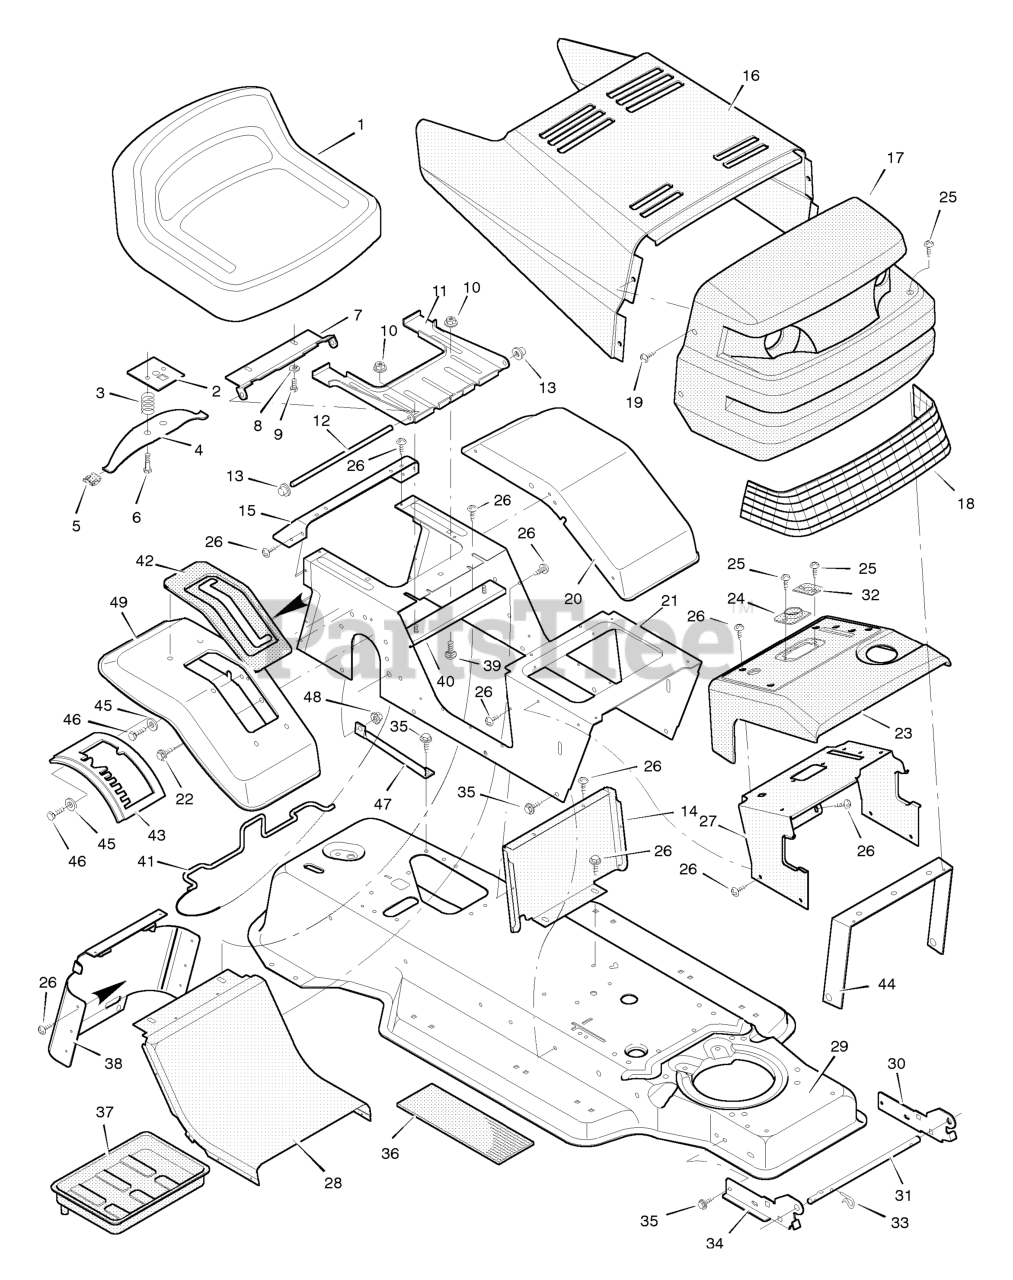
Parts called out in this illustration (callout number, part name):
2	Plate Assembly, Switch
3	Spring, Compression
4	Spring, Seat
5	Glide, Spring
6	Bolt, Shoulder
7	Support, Seat
8	Lockwasher
9	Bolt, Hex
10	Locknut, Flange
11	Bracket, Pivot
12	Rod, Pivot
13	Cap, Push On
14	Insert, Front
15	Fender, Apron
17	Grille Assembly
21	Console Assembly
23	Dash Panel
24	Bearing, Steering
26	Screw
27	Support, Dash
28	Insert, Rear
29	Frame Assembly
30	Bracket, Left Grille
31	Rod, Pivot
32	Bearing
33	Pin, Hair
34	Bracket, Right Grille
37	Tray, Battery
38	Cap, Console
39	Bolt
40	Channel Assembly
41	Clamp, Battery
42	Cover, Shift
43	Gate, Shift
44	Brace, Grille
46	Bolt, Hex
47	Strut, Shifter
48	Locknut
49	Fender, SOG
